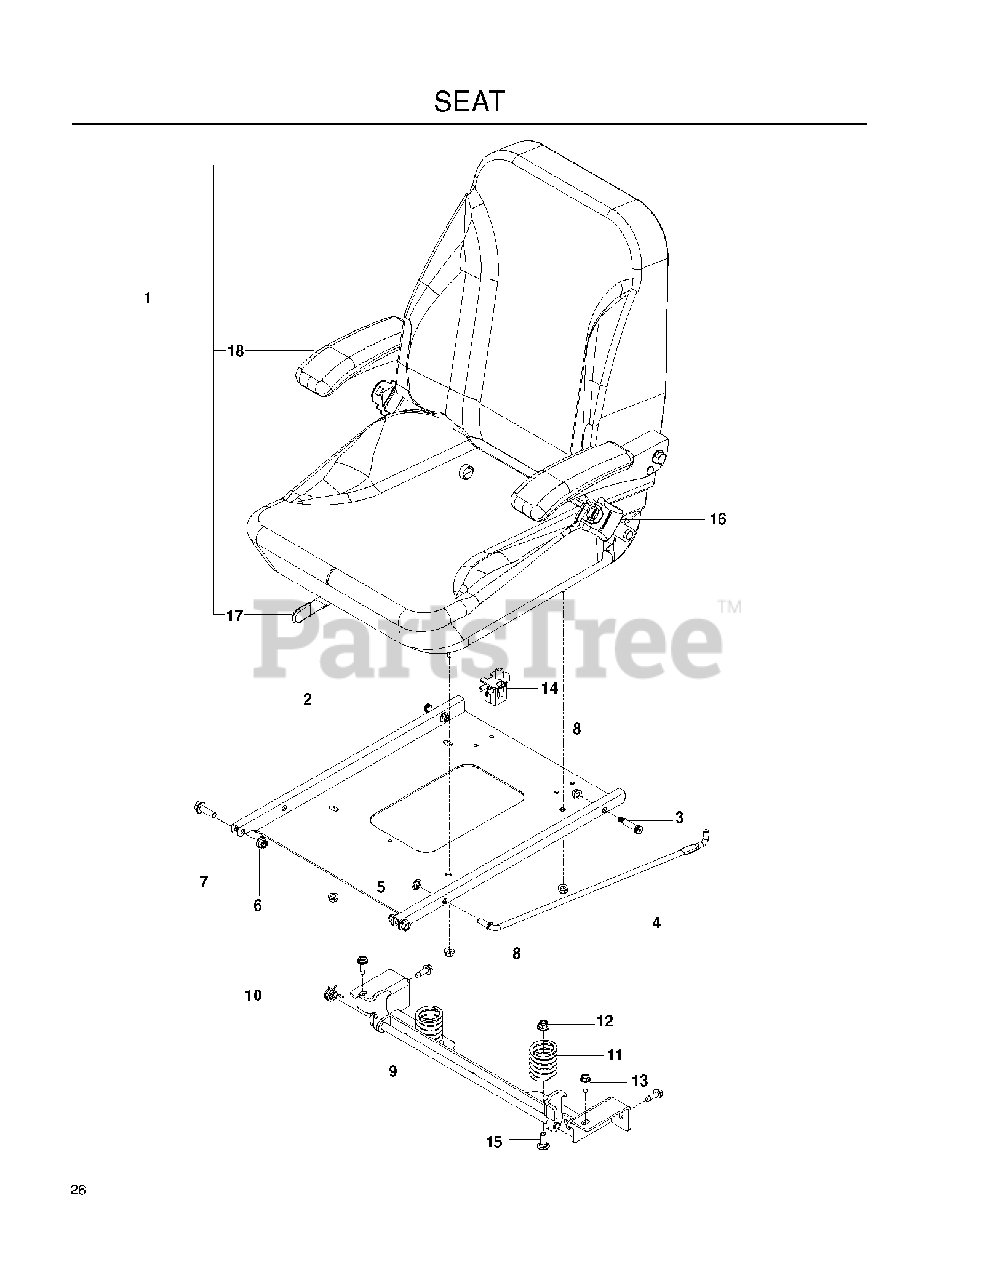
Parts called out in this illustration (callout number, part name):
1	SEAT ASSY
2	PAN, SEAT, BLACK
3	BOLT, SHOULDER 3/8 X 1.25
4	ROD, SEAT
5	BOLT RETAINER 3/8
6	NUT 3/8-16 HEX FLG NYLOC ZD
7	HHFS 3/8-16 X 1.25 GD 5
8	5/16-18 NYLOC FLANGE NUT
9	LATCH.SEAT.BLACK
10	SPRING, TORSION
11	SPRING, SEAT
12	NUT 3/8-16 HEX FLG NYLOC ZD
13	Hex Washer Head Bolt, 5/16-18 X 3/4 Thread Forming
14	SEAT SWITCH
15	RHSNB 3/8C X 1
16	SEAT BELT - RETRACTABLE
17	TRACK KIT
18	ARMREST, LT
18	ARMREST, RT
